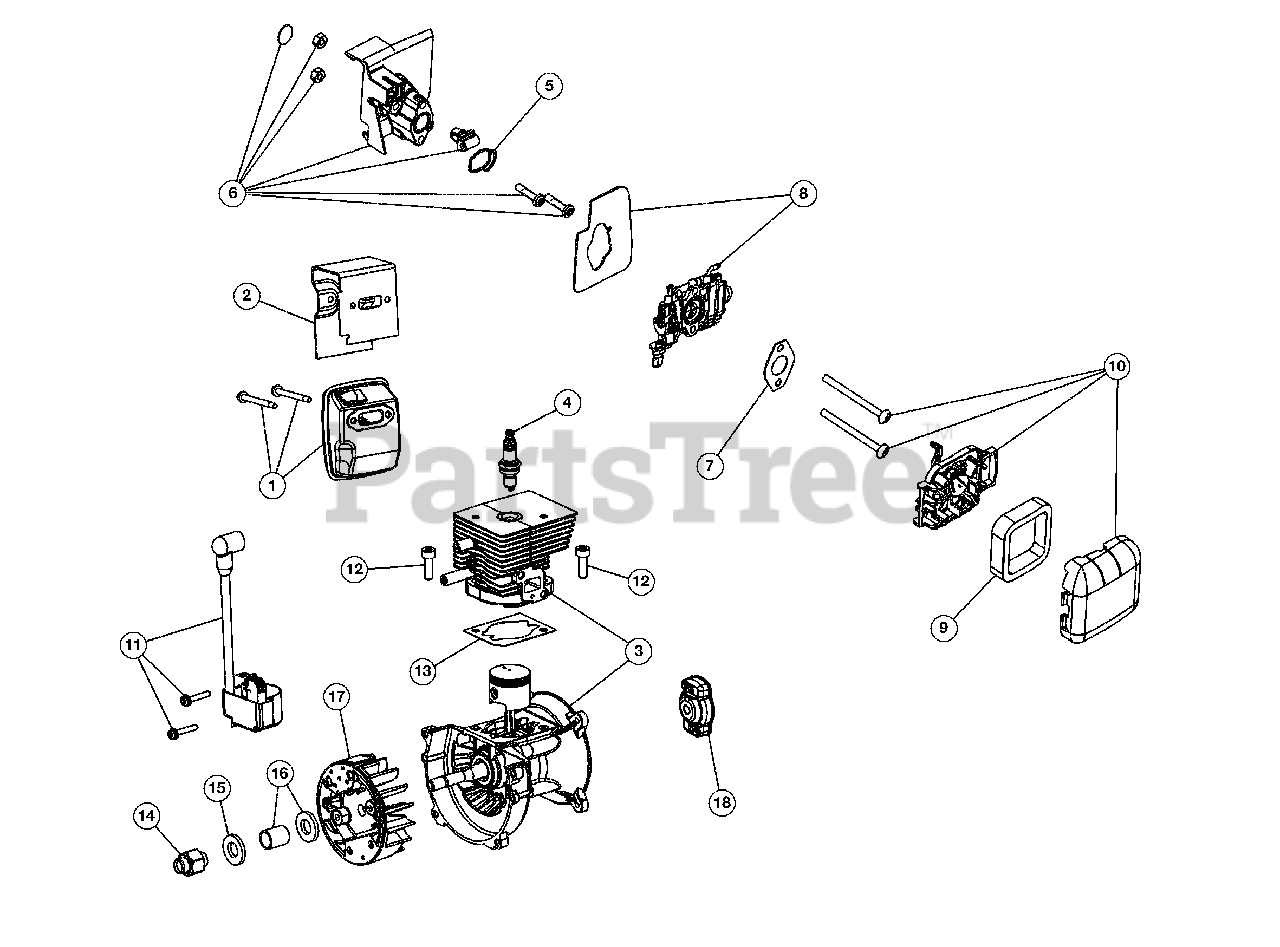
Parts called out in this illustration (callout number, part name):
1	Muffler Assembly (Incl. 2)
2	Muffler Gasket
3	Shortblock Assembly (Incl. 4 & 11-17)
4	Spark Plug
5	Insulator O-Ring
6	Insulator Assembly (Incl. 5)
7	Carburetor Gasket
8	Carburetor Assembly (Incl. 7)
9	Air Filter
10	Air Cleaner Assembly (Incl. 9)
11	Module Assembly
13	Cylinder Gasket
14	Flywheel Adaptor
15	Washer
16	Bushing
17	Flywheel Assembly
18	Pawl Assembly
